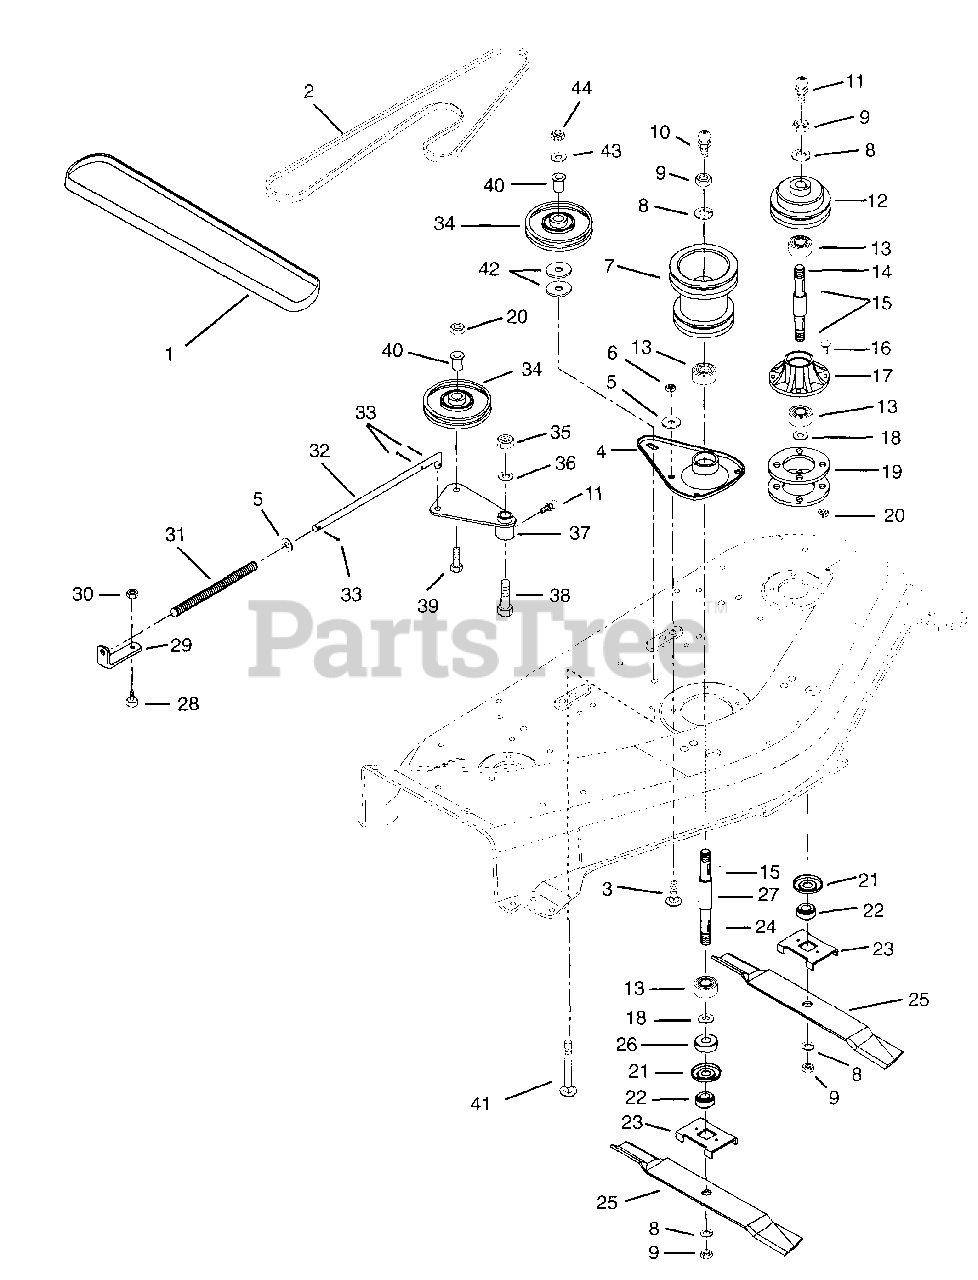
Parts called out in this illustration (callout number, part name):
1	V-BELT, HA-WRAPPED
2	V-BELT, HA-RAW EDGE
3	@BLT-RDHDSQNK .38-16X.75 G2YWZ
4	HOUSING,SPINDLE
5	@WSHR-FL-STL.406X.812X.065 YWZ
6	@NUT-LK-CTR .38-16 YWZC
7	SHEAVE, 48" DECK
8	@WSHR-LK .75X.188 REG YWZC
9	NUT-JAM .75-10 YWZC
10	FTG,LUBE 1/8
11	FTG-LUBE .25-28X.256 YWZC
13	BRG-BALL .750X1.781X.61
14	SPINDLE SHAFT W/ZERK
15	KEY-WDRF .188X.625X.25 SAE 61
16	@BLT-RDHDSQNK .38-16X.75 G2YWZ
17	SPINDLE HOUSING
18	WSHR-FL-STL .754X1.000X.032 YZ
19	SPACER, SPINDLE
20	@NUT-LK-CTR-JAM .375-16 YWZC
21	BEARING SLINGER
22	RETAINER HUB
23	BLADE TRAY 48
24	KEY-SQ .188X.625X.188 SAE 61
25	BLADE
26	WSHR-FL-STL .755X1.25X.125 YZ
27	SPINDLE SHAFT W/ZERK & KEY
28	@BLT-HEX .31-18X.50 GR5 YWZC
29	BRACKET
30	@NUT-LK-CTR .31-18 YWZC
31	SG-COMP .106X.63X 12.0 WLD 62
32	ROD-IDLER SPRING
33	@PIN-CTR .09X.75 EXTPRSQCT YWZ
34	IDLER, PLASTIC, 4.00 X .50 ID
35	@NUT-LK-CTR .50-13 YWZC
36	WSHR-FL-STL .505X.880X.072 YWZ
37	IDLER ARM W/ZERK
38	@BLT-HEX .50-13X1.50 GR5 YWZC
39	BLT-BTHD .38-16X1.25 GR5
40	SPACER -FLANGED .390X.500X.781
41	@BLT-RDHDSQNK .38-16X2.00 G2YZ
42	WSHR-FL-STL .390X1.5X.125 YWZC
43	@WSHR-FL-STL.38X.875X.083 YWZC
44	NUT-LK-CTR .375-16 YWZC
